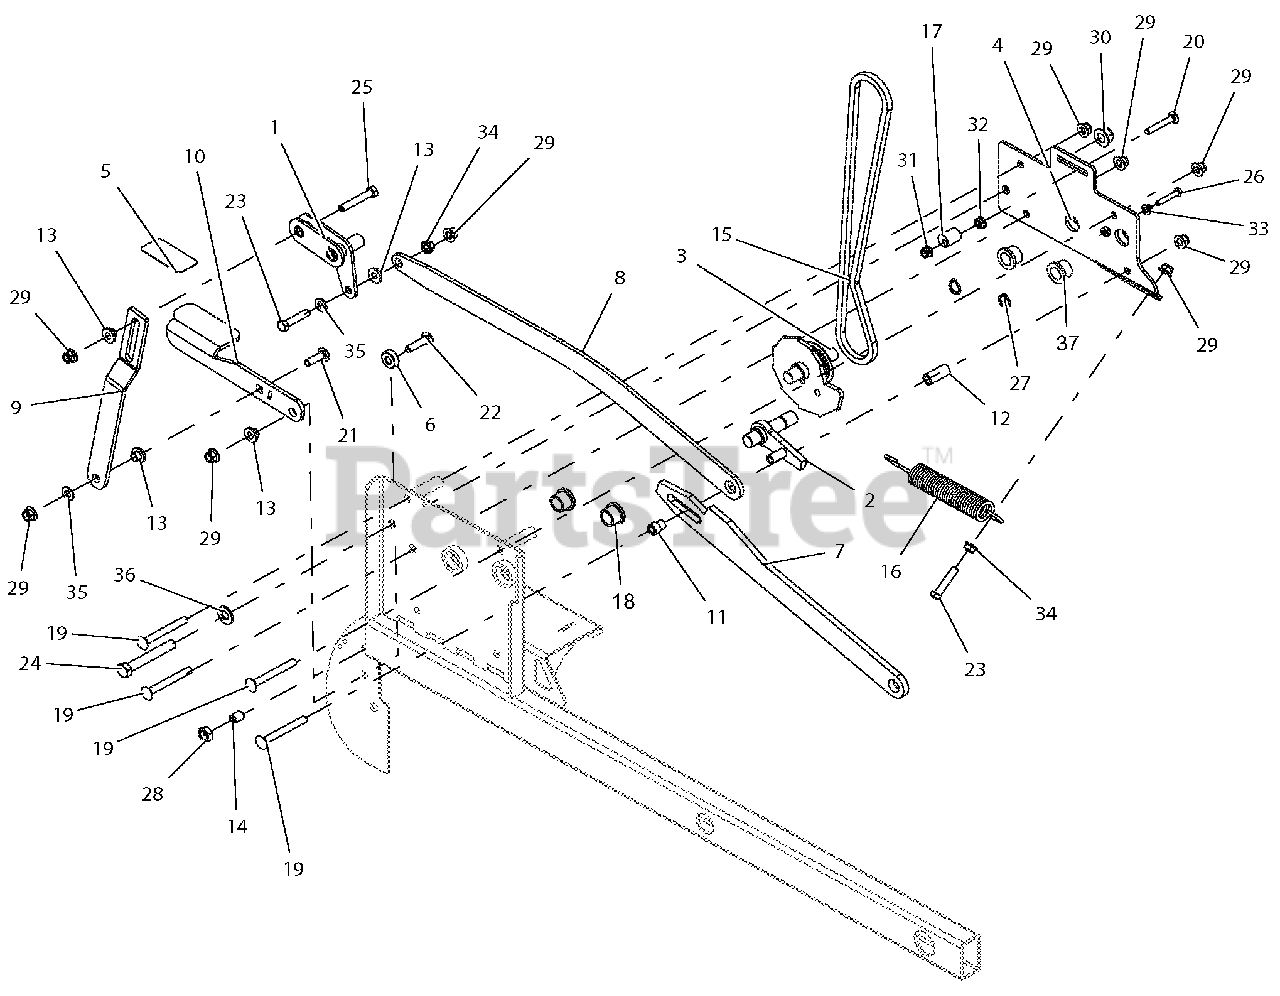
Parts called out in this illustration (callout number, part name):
1	W LDMT, REAR PEDAL PIVOT
2	W LDMT, TRAILER LOCK
3	W LDMT, HOC CAM
4	W LDMT, CAM COVER
5	GRIP, PEDAL 1.50 X 3.00
6	SPCR, .375 X 1.00 X .342
7	ARM, CAM CONTACT
8	ARM, PEDAL
9	ARM, PEDAL
10	PEDAL, DECK LIFT FOOT-BLACK
11	BSHG, FLG .385 X .500 X .812 X .437
12	SPCR, .385 X .625 X 1.438
13	BSHG, FLG .385 X .500 X .875 X .406
14	BALL SPRING PLUNGER, .500-13
15	BELT, 5MM HTD
16	SPRG, TENSION .162 X 1.250 X 8.250
17	ECCENTRIC
18	BUSHING, .750 X 1.00 X .750
19	BLT-RDHDSQNK .38-16X3.25 G5 Y
20	BLT-RDHDSQNK .31-18X2.0 FTH G5
21	BLT-RHDSSQNK .38-16X1.25 G5YZ
22	BLT-RHDSSQNK .38-16X1.50 G5YZ
23	BLT-HEX .38-16X1.75 GR5 YWZC
24	BLT-HEX .50-13X3.50 GR5 YWZC
25	BLT-HEX .38-16X2.25 GR5 YWZC
26	BLT-HEX .25-20X1.50 GR5 YWZC
27	RG-RTNG-EXT .750x.078
28	NUT, JAM .500-13 YWZC
29	NUT-LK-NYL-FLG .38-16 YWZC
30	NUT-LK-NYL-FLG .50-13 YWZC
31	NUT-LK-NYL-FLG .31-18 YWZC
32	@ NUT-SPNLK-FLG .312-18 YWZC
33	@ NUT-SPNLK-FLG .25-20 YWZC
34	@ NUT-SPNLK-FLG .375-16 YWZC
35	W SHR-FL-STL.406X.812X.065 YW
36	W SHR-FL-STL.531X1.06X.095YWZC
37	BUSHING, .750 X 1.00 X .750
